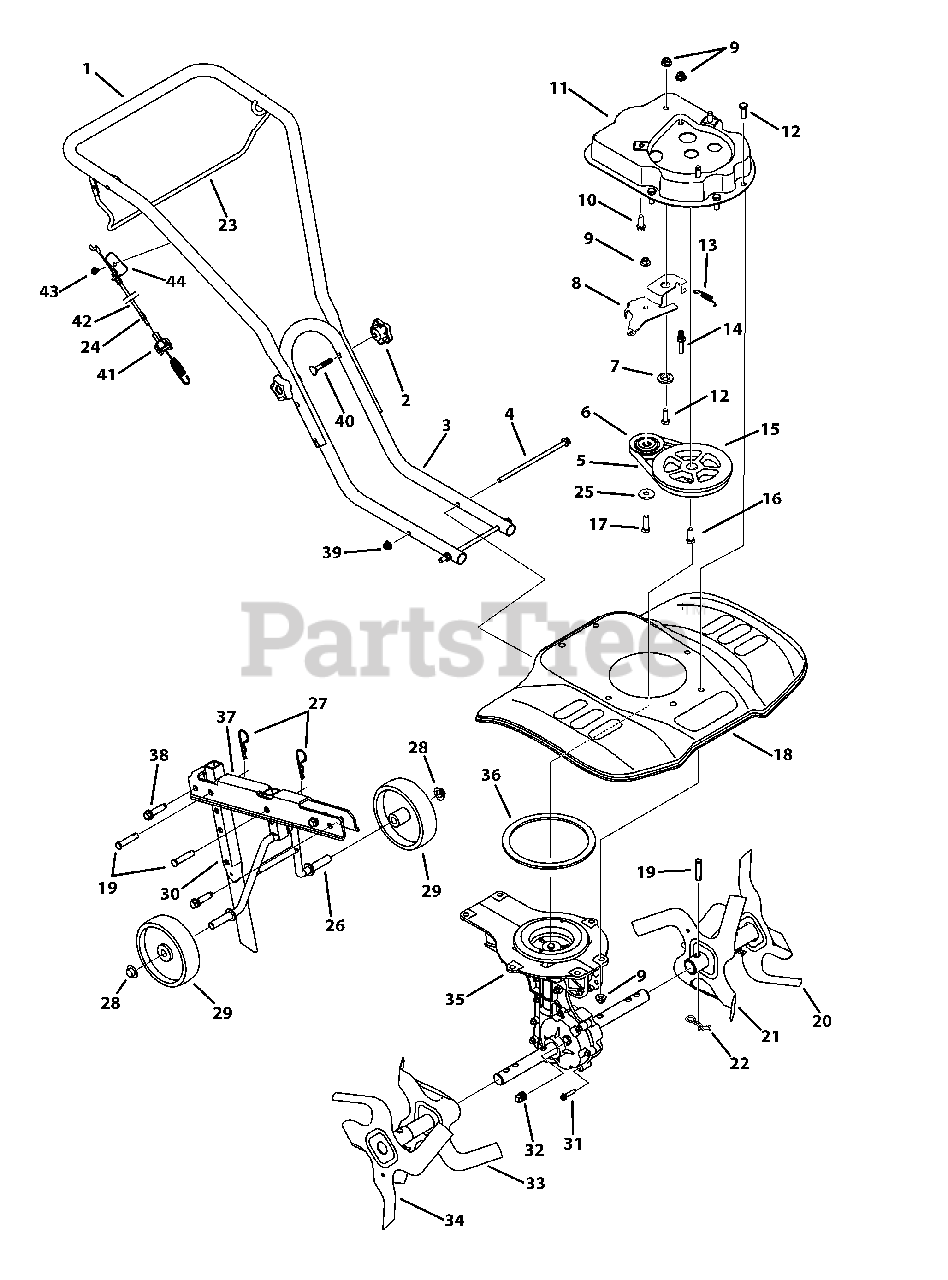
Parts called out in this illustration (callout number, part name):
1	Upper Handle
2	Star Handle Knob
3	Lower Handle
4	Flange Screw: 5/16-18:7.5:GR5
5	V-Belt
6	Idler Pulley
7	Shoulder Spacer
8	Idler Bracket
9	Flange Lock Nut: 3/8-16
10	TT Screw: 3/8-16:1.00
11	Belt Cover
12	Hex Cap Screw: 3/8-16:1.00
13	Extension Spring
14	Stud: 33 x 1.5: 3/8-16
15	Flywheel Pulley
16	Hex Cap Screw: 3/8-24:1.00
17	Hex Cap Screw: 3/8-16:1.55
18	Tine Shield 61 cm
19	Clevis Pin
20	Outer Tine Assembly LH
21	Inner Tine Assembly LH
22	Cotter Pin, Bow Tie
23	Clutch Bail
24	Retaining Ring
25	Flat Washer, .406 x .875 x .059
26	Rear Wheel Tube Assembly
27	Cotter Pin
28	Push Cap
29	Wheel 5 x 1.38
30	Depth Stake Tube
31	TT Screw: 1/4-20:1.25
32	Pipe Plug: 3/8 NPT
33	Inner Tine Assembly RH
34	Outer Tine Assembly RH
35	Case Assembly
36	Gasket
37	Wheel Bracket
38	TT Screw: 3/8-16:1.50
39	Flange Lock Nut: 5/16-18
40	Carriage Bolt
41	Clutch Cable Fitting
42	Clutch Cable
43	TT Screw: 1/4-20:.50
44	Cable Mount Bracket
